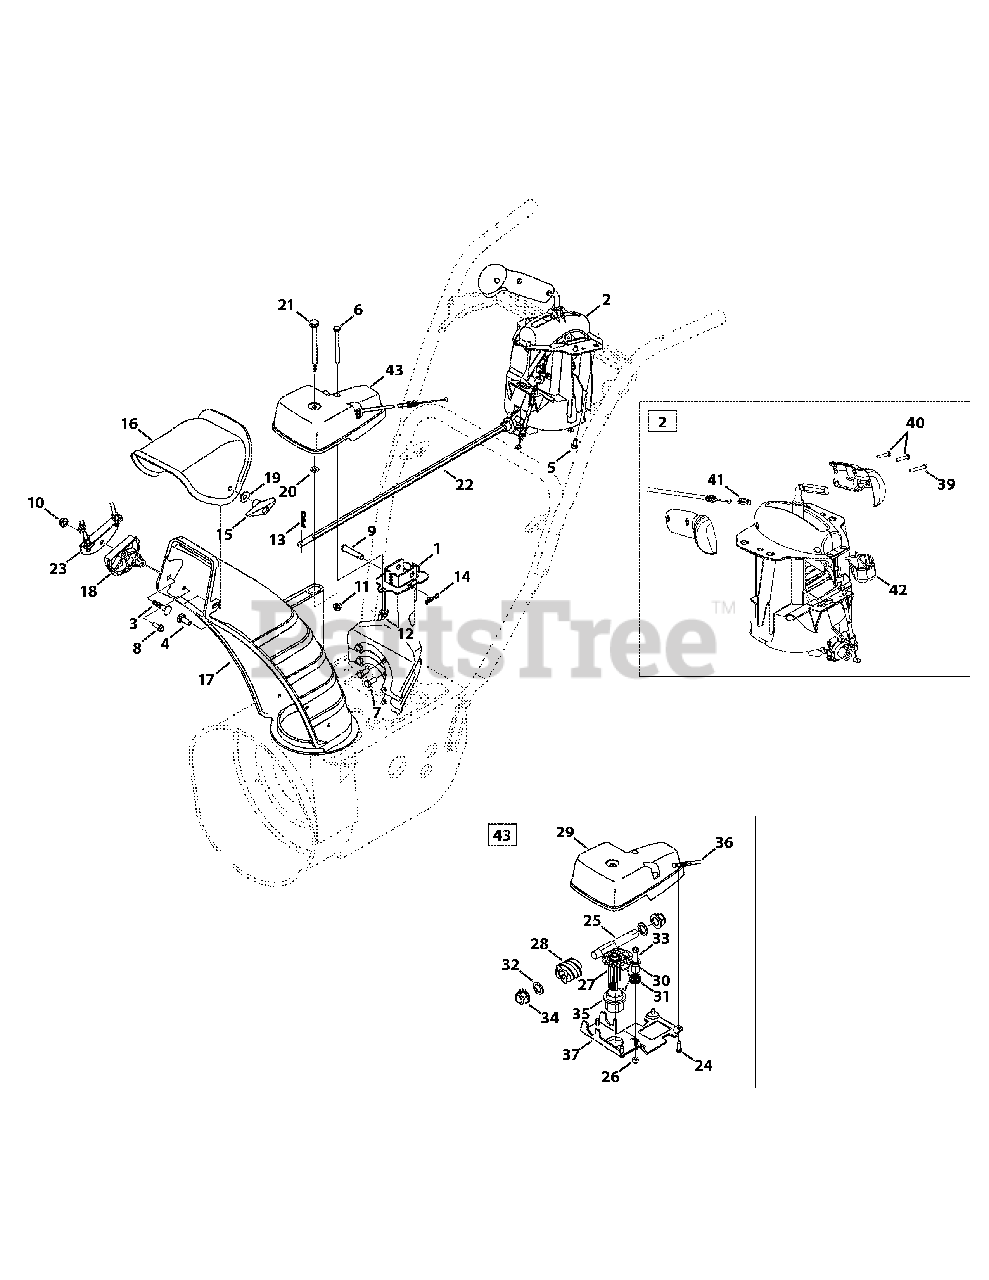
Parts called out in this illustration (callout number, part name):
1	Chute Support Bracket
2	Chute Control, 4-Way
2	Chute Control, 2-Way
2	Control Trigger Housing Kit
3	Bolt, Carriage, 5/16-18 x 1.50 - 28" Models
3	Bolt, Carriage, 5/16-18 x .750 - 24" & 26" Models
4	Bolt, Carrier, 5/16-18 x 1.00
5	Screw, HL, 1/4-15 x 0.50
6	Hex Head Screw, 1/4-20 x 3.00
7	Hex Head Screw, 5/16-24 x .750
8	Screw, HL, 1/4-15 x 0.750
9	Clevis Pin, 3/8 x 1.87
10	Nut, Flangelock, 5/16-18
11	Nut, Flangelock, 1/4-20
12	Wing Nut, 1/4-20
13	Internal Cotter Pin
14	Bow-Tie Cotter Pin
15	Star Knob, 5/16-18
16	Chute, Upper Remote
16	Chute, Upper Manual Tilt
17	Chute, Lower
18	Cable Guide, Chute Tilt
19	Washer, Flat, .349 x .879
20	Washer, Flat, .25 x .630
21	Screw, Shoulder, .312 x 3.5 x 1/4-20
22	Chute Rod, 3/8 Hex
23	Cable Bracket
24	Screw, 12-16 x .75
25	Hex Shaft
26	Hexlock Nut, 1/4-28
27	Gear, 14T
28	Worm Gear
29	Gear Cover
30	Pawl Lock
31	Torsion Spring, .721 ID x .474
32	Washer, Flat, .625 x 1.0 x .067
33	Screw, Shoulder, .340 x .950 x 1/4-28
34	Hex Bearing
35	Flange Bearing
36	Cable Lock
37	Gear Bracket
39	Screw, #8 x 1.00
40	Screw, 8-32 x .750
41	Joystick Plug
42	Joystick Trigger
43	Chute Rotation Gearbox
